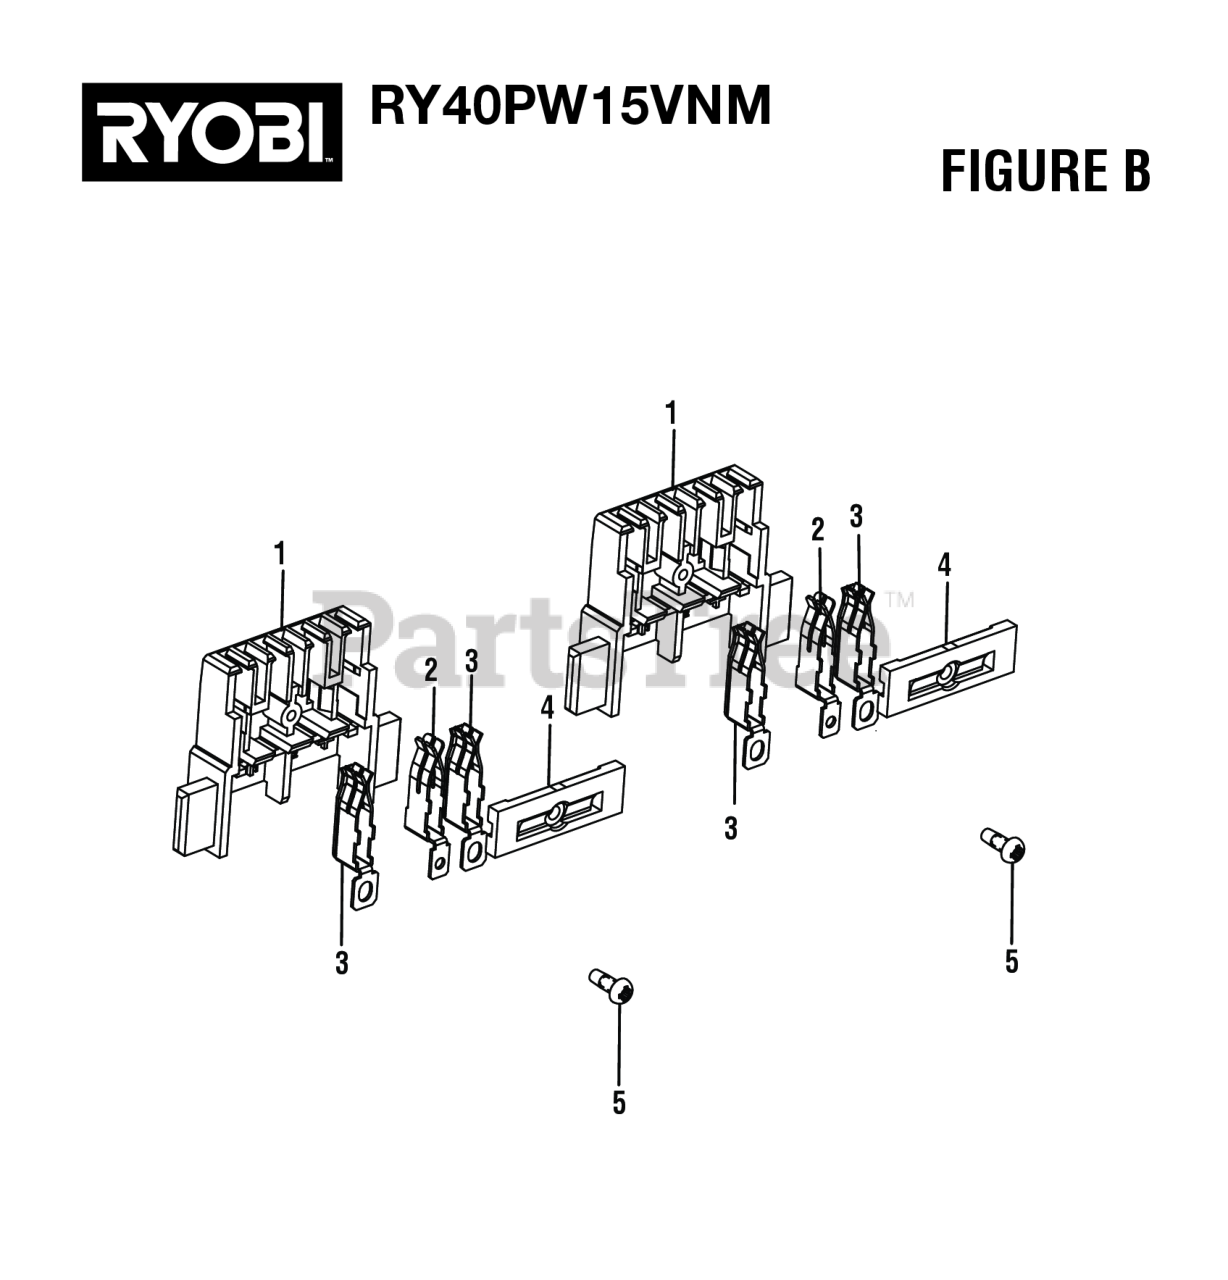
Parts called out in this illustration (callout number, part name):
1	Battery Contact Holder
2	STAMPING I BATTERY CONTACT PLATE TERMINA
3	Contact Plate Terminal
4	Battery Cover Connector
5	Screw (M3 x 8 mm, Pan Hd., Pan Hd)
